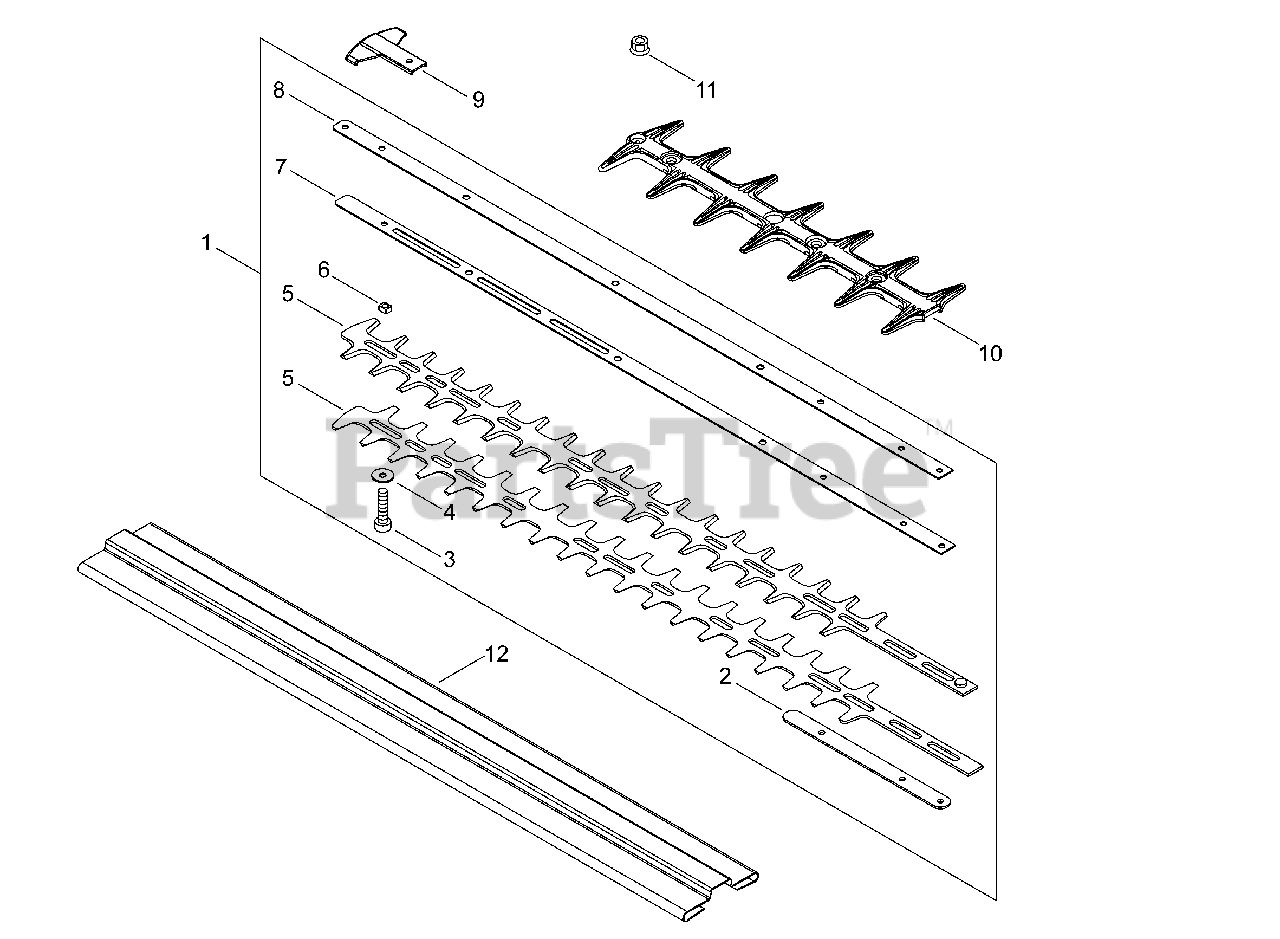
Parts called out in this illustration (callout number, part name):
1	CUTTER ASSY, 24"
2	PLATE, EYE
3	BOLT, TORX 5×25
5	BLADE, TRIMMER
6	GUIDE, BLADE 5
7	SUPPORT, BLADE
8	SUPPORT, BLADE
9	GUARD, TIP
10	GUARD, CUTTER BLADE
11	NUT, FLANGE M5
12	SCABBARD 24"
